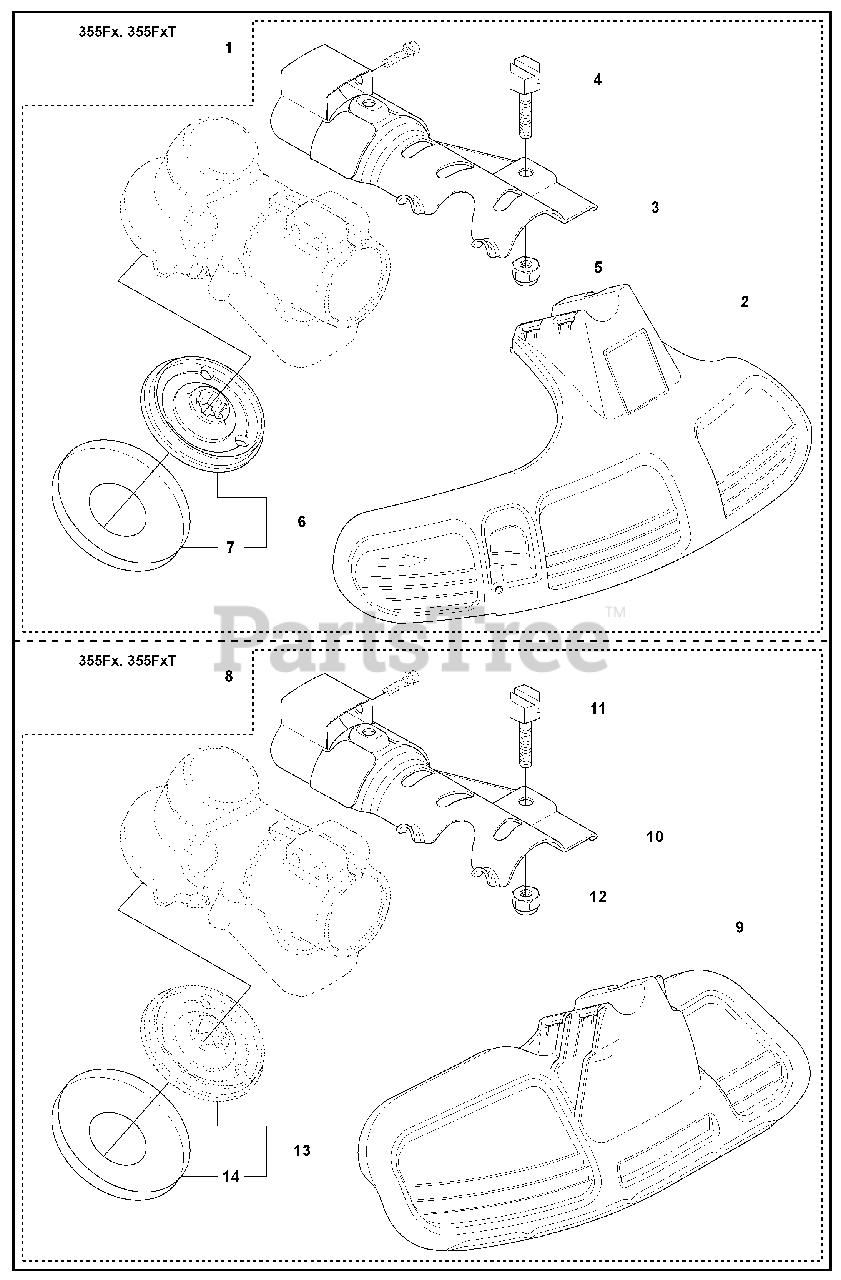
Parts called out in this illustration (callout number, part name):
2	PROTECTION
3	ATTACHMENT PLATE
5	LOCKNUT M6
7	GRASS SEALING
9	BLADE GUARD GRASS
10	ATTACHMENT PLATE
12	LOCKNUT M6
14	GRASS SEALING
